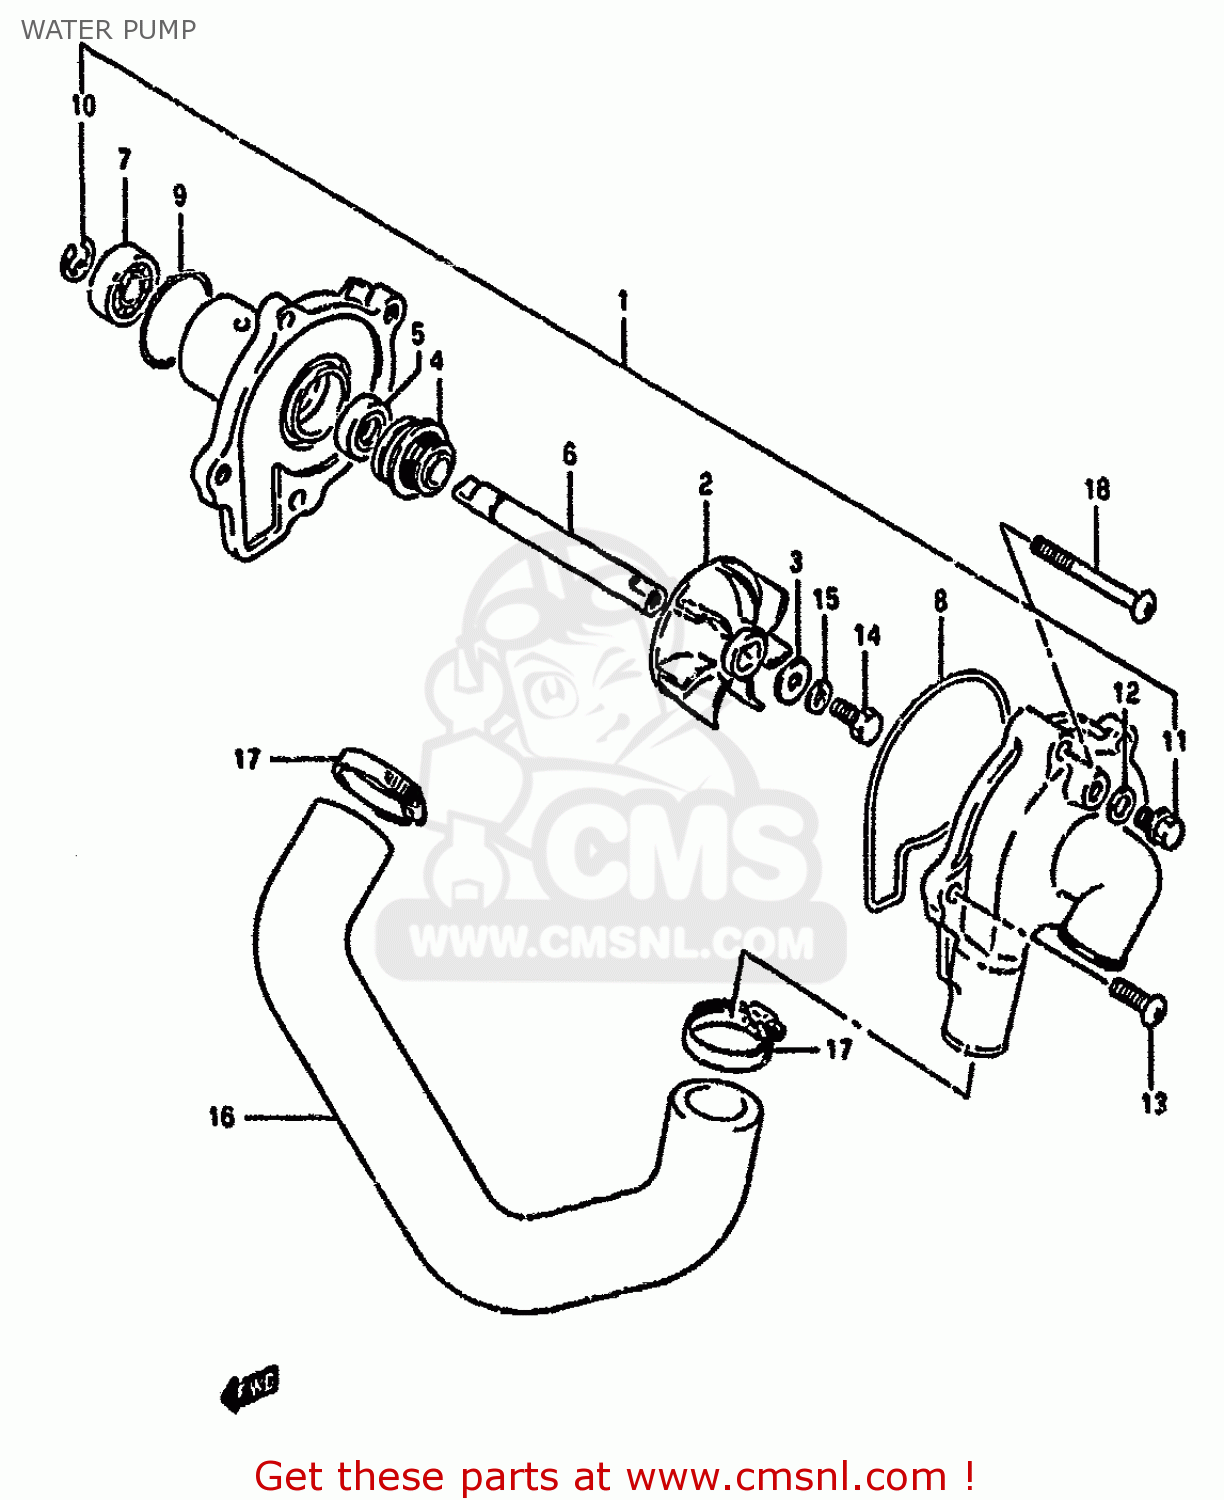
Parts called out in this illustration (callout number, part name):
1	PUMP ASSEMBLY,WATER
2	IMPELLER,WATER PUMP
3	GASKET(6X15X2.2) (NAS)
4	SEAL,MECHANICAL
5	OILSEAL
6	SHAFT,WATER PUMP
7	BEARING,10X26X8
8	O RING
9	O RING,WATER PUMP HOLDER
10	E RING
11	BOLT,DRAIN
12	GASKET 8.2X14X1 (NAS)
13	SCREW
14	BOLT(6X13)
15	WASHER
16	HOSE,WATER PUMP OUTLET
17	CLAMP
18	SCREW
